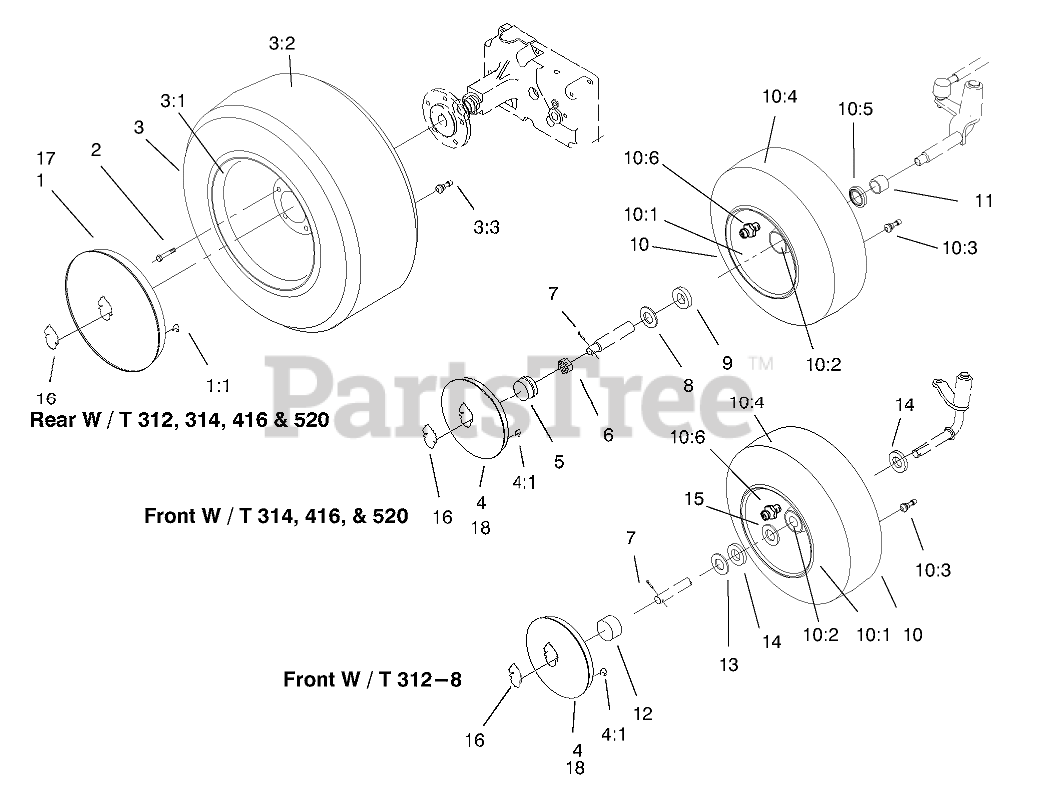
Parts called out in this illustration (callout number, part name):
1	HUBCAP - 12"
1:1	CLIP - HUBCAP
2	BOLT-LUG
3	ASM-Wheel & Tire
3:1	WHEEL
3:2	TIRE
3:3	VALVE
4	HUBCAP - 8"
4:1	CLIP - HUBCAP
7	PIN-COTTER
10	FRONT WHEEL ASM
10:1	Wheel ASM
10:2	BEARING-WHEEL
10:3	VALVE
10:4	Tire (16 x 6.5-8) 2-Ply -2 Wheel Axel
10:6	ZERK-GREASE
12	HUBCAP
13	WASHER WHEEL
14	WASHER
15	WASHER-SHIM
16	LOGO - HORSEHEAD
17	HUBCAP ASM - 12", YGT (HORSEHEAD LOGO)
17:1	HUBCAP - 12"
17:2	LOGO - HORSEHEAD
18	SILVER HUB CAP/LOGO ASM
18:1	HUBCAP - 8"
18:2	LOGO - HORSEHEAD
